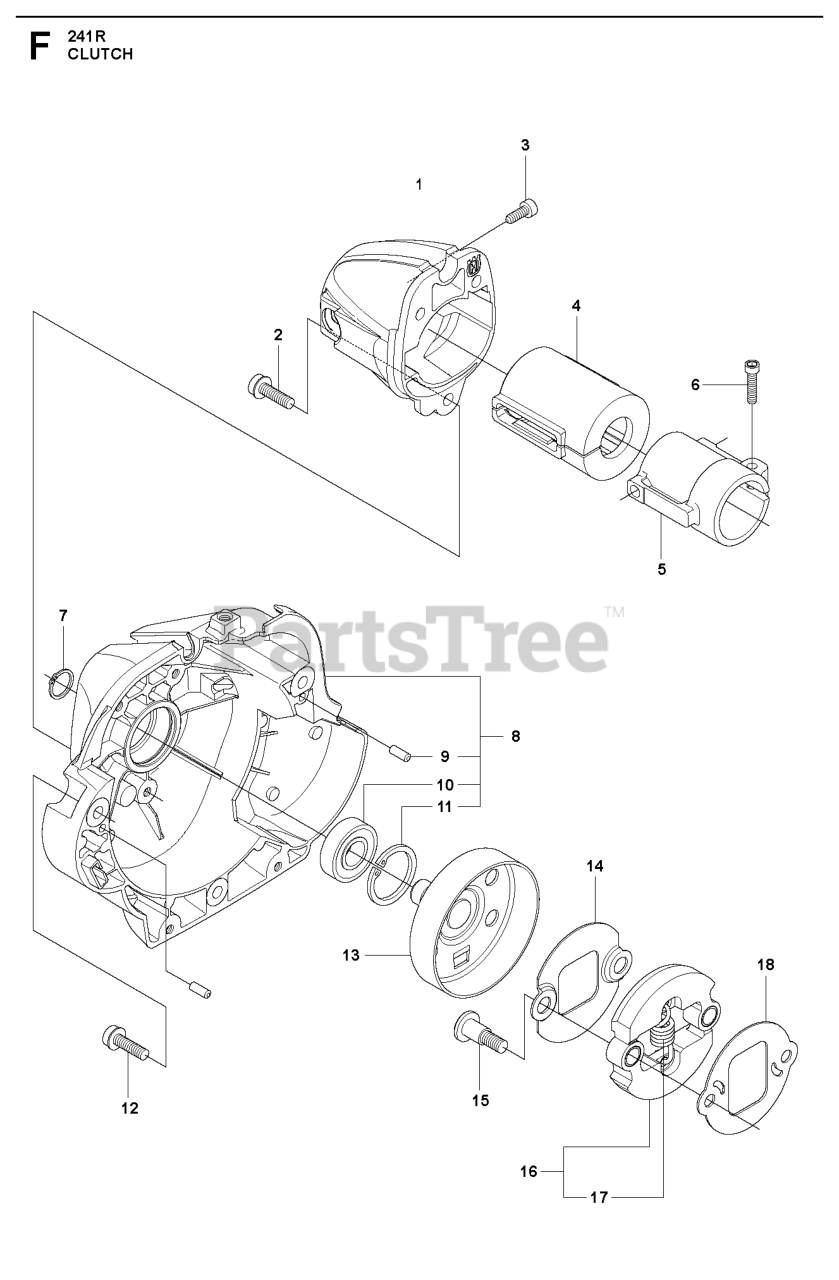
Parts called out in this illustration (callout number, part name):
2	SCREW IHSCFM
3	SCREW IHSCT
4	VIBRATION ABSORBER
5	SLEEVE, COVER
6	SCREW MC6S 5X25
7	SEEGER CLIP
8	CLUTCH COVER KPL
10	BALL BEARING
11	RETAINING RING SGH 28
12	SCREW IHSCFM
13	CLUTCH DRUM
15	SCREW CLUTCH
16	CLUTCH CPL
18	WASHER
